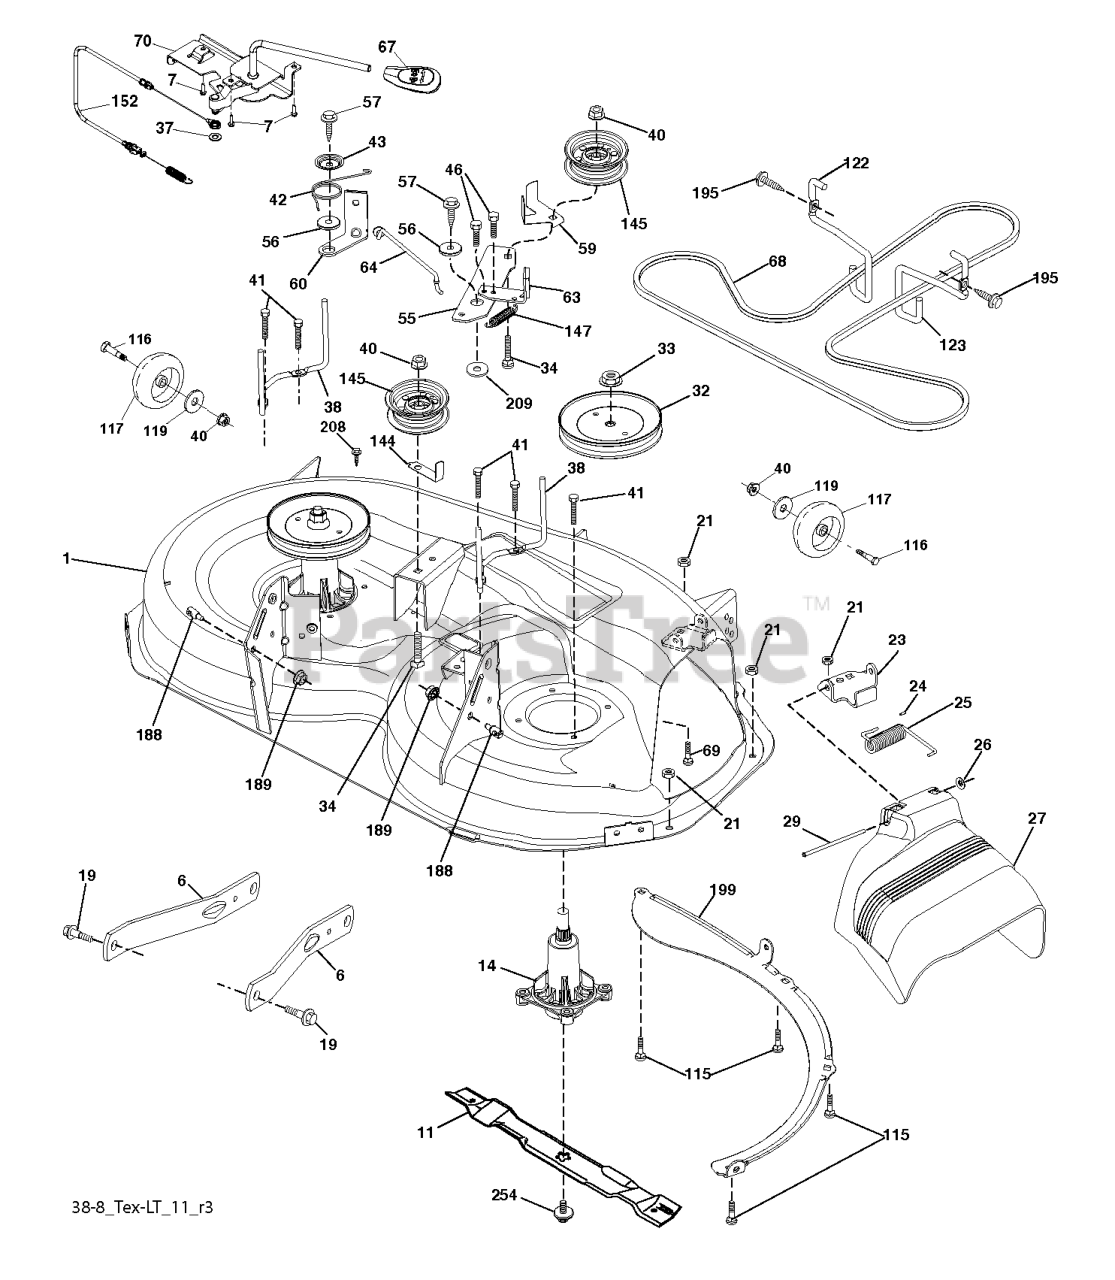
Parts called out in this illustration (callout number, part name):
1	DECK.SVC.WLDT.38"
6	ARM.SUSPENSION.MOWER.R
11	BLADE.2 IN 1.38"DECK.BLACK
14	KIT.MANDREL.NONGREASE.TALL
19	BOLT.SHOULDER
23	BRKT.DEFLECTOR.38"2005+
24	CAP-SLEEVE LT
25	SPRING.TORSION.DEFLECT
26	NUT PUSH M
27	SHIELD, DEFLECTOR
32	PULLEY.MANDREL.5.0.PD.38"
34	GSPW Bolts
37	WASHER PLAIN WASHER 3/8 X 0.08
38	KEEPER BELT LH MANDREL
40	NUT LOCK FLG 3/8-16 UNC
41	BOLT.HEX.WASHR.HED.313-18X1.19
42	SPRING.TORSION.BRAKE
43	SRPING.TORSION.RETAINE
46	SCREW.1/4-20X5/8
56	SPACER.RETAINER
57	SCREW 3/8-16X1
59	GUARD, BELT
60	ARM BRAKE MOWER RH 38"
63	RP ARM.BRAKE.MOWER.38"LH.TEX
64	LINKAGE.BRAKE.ASM.ZINC
67	HANDLE.CLUTCH.CABLE.LT
70	CLUTCH.ASM.MANUAL.LT.PRED
115	BOLT ROUND HEAD SQUARE NECK BO
117	WHEEL.GAUGE.RALLY.NARROW
122	KEEPER BELT ENGINE LH
123	KEEPER BELT RH
144	KEEPER BELT
145	PULLEY.IDLER.48"PRIMARY
147	SPRING RETURN
152	CABLE.CLUTCH.MANUAL.
188	STUD.W/"D"ANTI-ROTATION
195	SCREW, 3/8-16X3/4
199	BAFFLE.VORTEX.FRONT.38"
208	SCREW 3/8-16X1/2
254	SCREW.SEMS.7/16-20X1.HEX.HEAD
